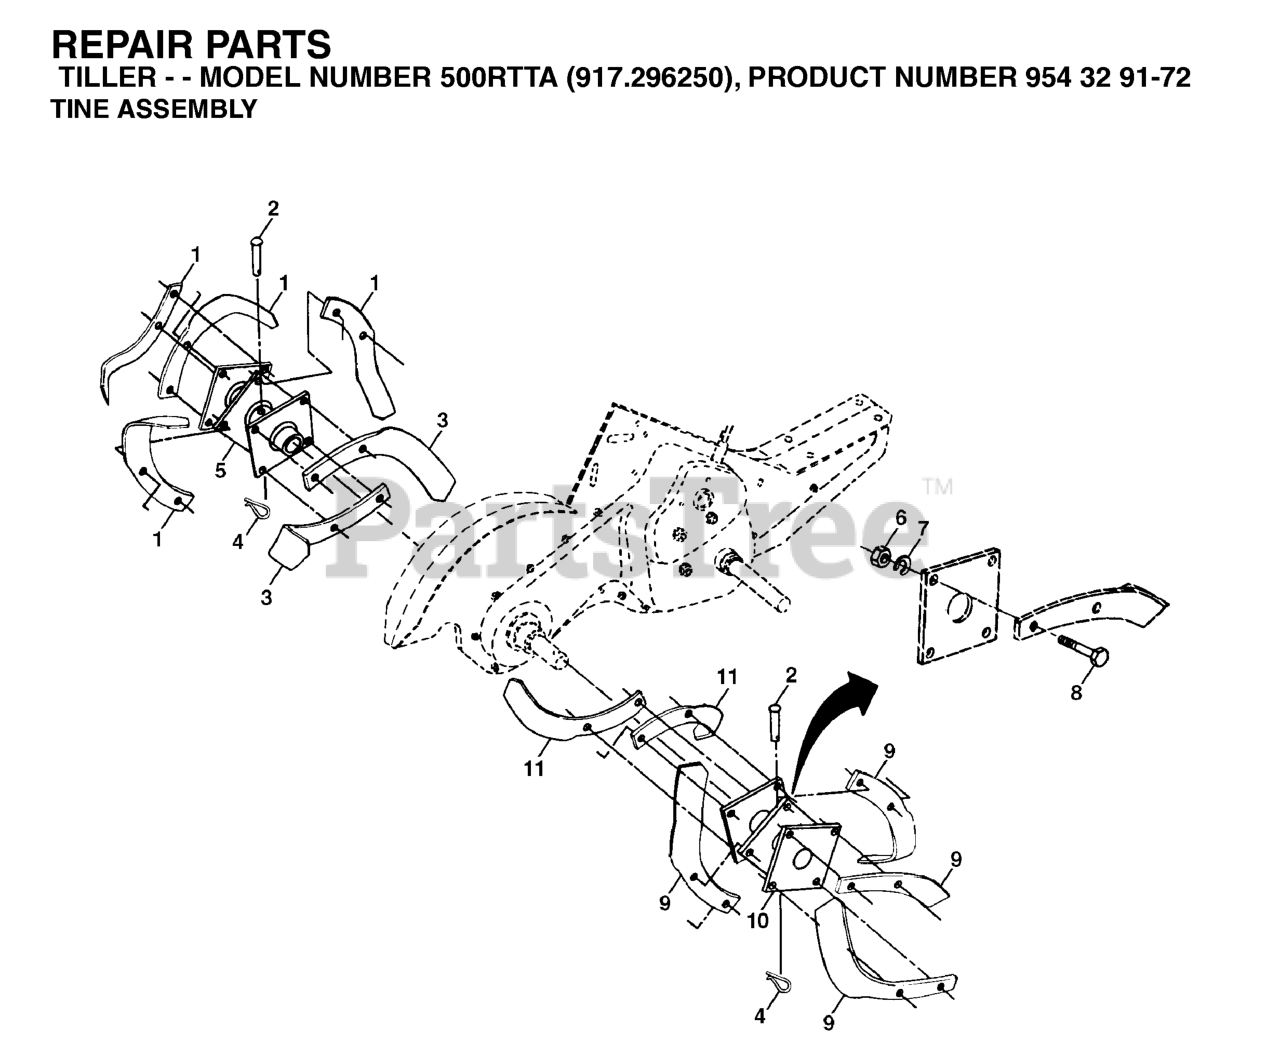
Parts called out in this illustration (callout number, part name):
1	TINE TI
2	PIN RETAINING SCREW
3	TINE.LH.12"(72L)
4	SPRING RETAINER
5	HUB.&.PLATE.ASM.LH
6	NUT
7	WASHER, LOCK 3/8
8	BOLT.HEX.001X20.37-24X1.ZINC
9	TINE TI
10	HUB & PLATE ASM RH
11	TINE.RH.12"(72R)
